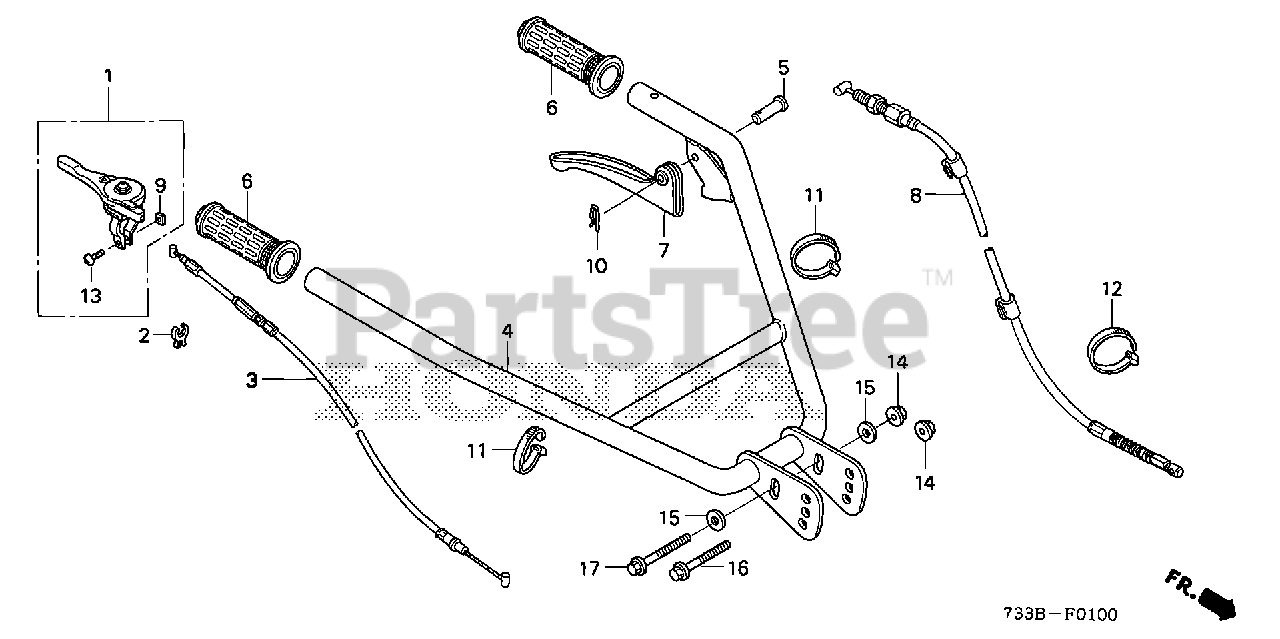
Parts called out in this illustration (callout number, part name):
1	LEVER ASSY., THROTTLE
2	CLIP, THROTTLE
3	CABLE, THROTTLE
4	PIPE, HANDLE
5	PIN, EXCHANGE (8X21)
6	GRIP, R. HANDLE
7	LEVER, CLUTCH
8	CABLE, MAIN CLUTCH
9	NUT, SQUARE (5MM)
10	PIN, SNAP (7MM)
11	BAND, CABLE (120MM) (BLACK)
12	BAND, SUCTION HOSE (BLACK)
13	SCREW, PAN (5X20)
14	NUT, FLANGE (10MM)
15	WASHER, PLAIN (10MM)
16	BOLT, FLANGE (10X80)
17	BOLT, FLANGE (10X85)
